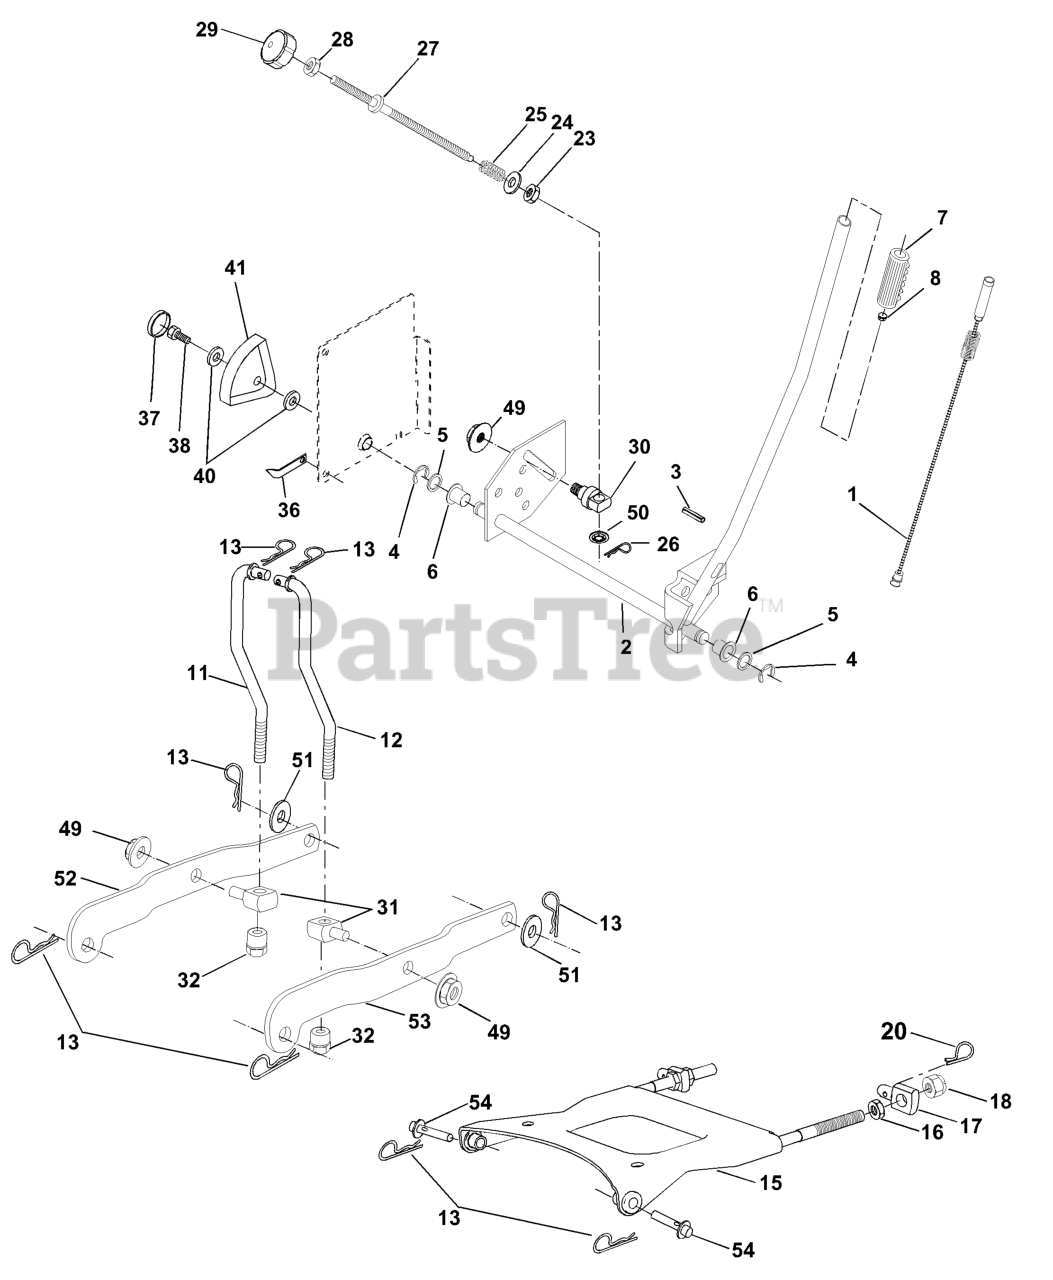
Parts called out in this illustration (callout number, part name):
1	WIRE ASM INNER W/ PLUNGER LT
2	SHAFT ASM R HANDLE
3	PIN GROOVE.
4	RETAINING RING LT
6	BEARING.NYLON
7	GRIP HANDLE
8	PLUNGER BUT KIT
11	LIFT LINK LH
12	LIFT LINK RH
13	RETAINER-SPRNG RB
15	PLATE ASM SUSP FRONT
16	NUT.HEX.JAM.1/2-13
18	NUT.LK.W/WSH.1/2.
20	SPRING RETAINER
25	SPRING**
26	RETAINER CLIP
27	ROD ADJ LIFT
28	NUT
29	KNOB INF 3/8-16
32	NUT, LIFT LINK 7/16-20
36	POINTER, HEIGHT INDICATOR(2 2)
38	SCREW 5/16-18X1
41	IND. HEIGHT STLT
49	NUT
50	NUT PUSH M
51	Washer 17/32 x 7/8 x 16 Ga.
52	ARM SUSP. REAR LH
53	ARM SUSP REAR RH
54	PIN.FLANGE
